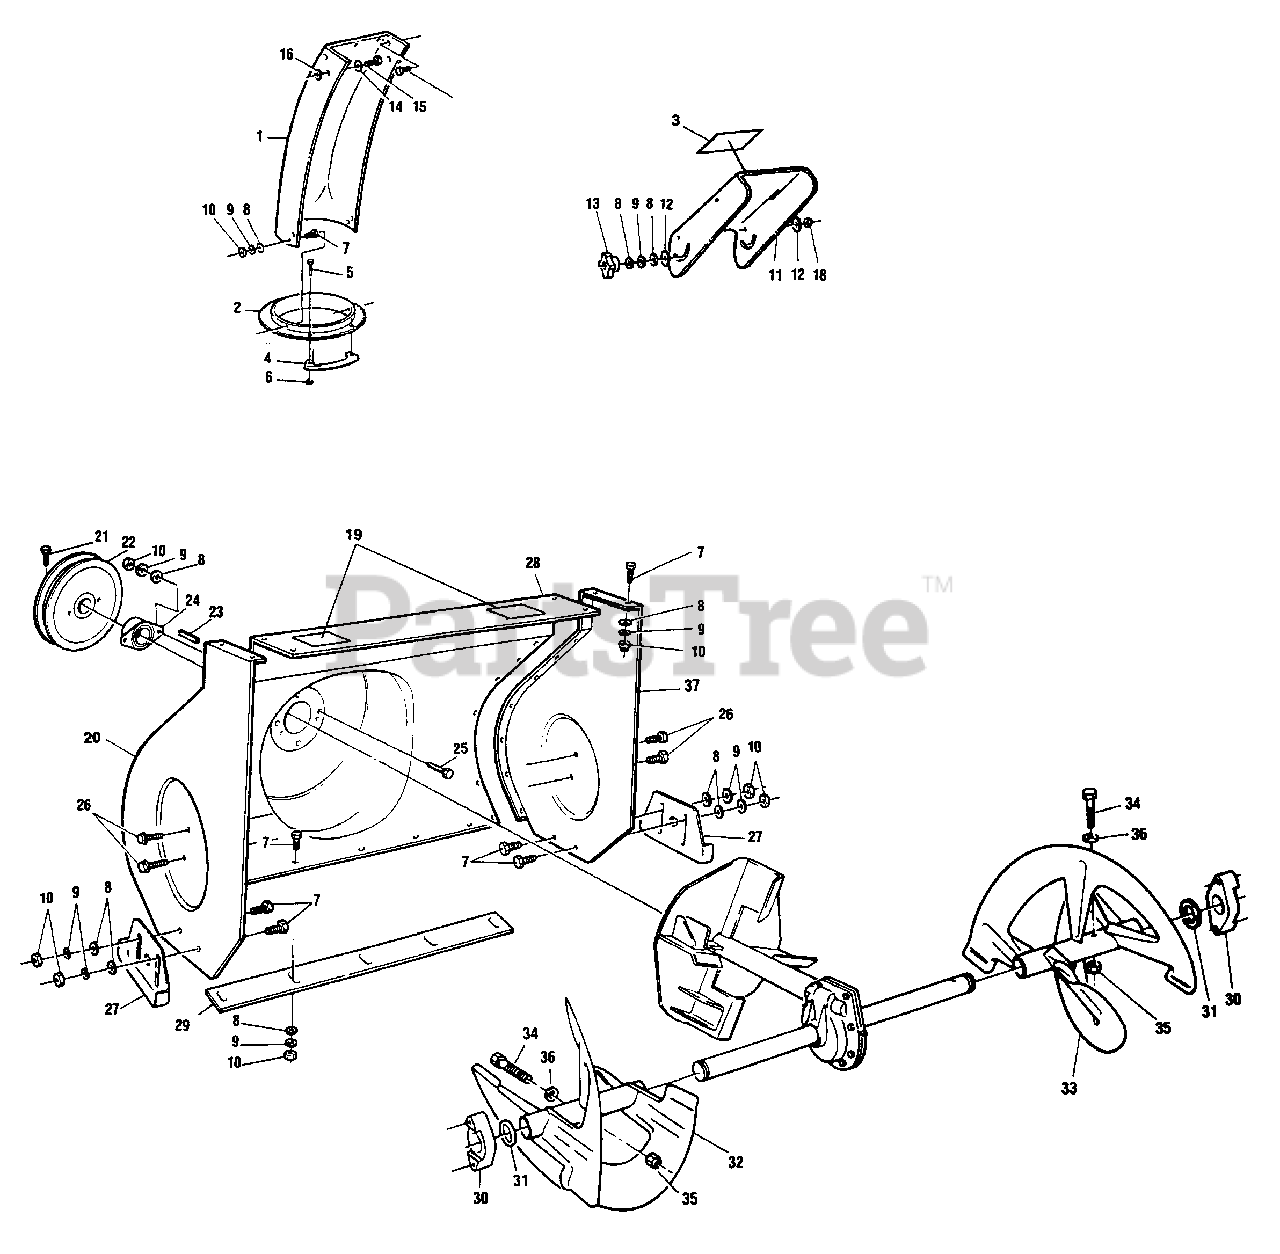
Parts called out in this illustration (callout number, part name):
1	EXTENSION - Chute
4	RETAINER
5	BOLT - 8-32 x 1/2
6	NUT - Lock 8-32
7	BOLT - Carriage 5/16-18 x 3/4
8	WASHER - Flat 5/16
9	WASHER - Lock 5/16
10	NUT - Hex 5/16
11	DEFLECTOR - Chute
12	WASHER - Plastic
13	KNOB - Wing
14	WASHER - Flat 7/16
15	BOLT - Carriage 5/16-18 x 1
16	WASHER - Flat 3/8
18	NUT - Lock 5/16-18
20	PLATE - Side (R.H.)
21	BOLT - 5/16-18 x 3/4
22	PULLEY - Auger 6.5"
23	KEY - 3/16
24	BEARING 7/8
25	BOLT - 5/16-18 x 5/8
26	SCREW - Self Tapping 5/16-18 x 3/4
27	HEIGHT ADJUSTOR
28	HOUSING - 23" Auger (Red)
29	BAR - 23" Scraper
30	SHAFT - Auger Bushing
32	AUGER - 23" R.H.
33	AUGER - 23" L.H.
34	BOLT - 1/4-20 x 1-1/2
35	NUT - Lock 1/4-20
37	PLATE - Side (L.H.)
